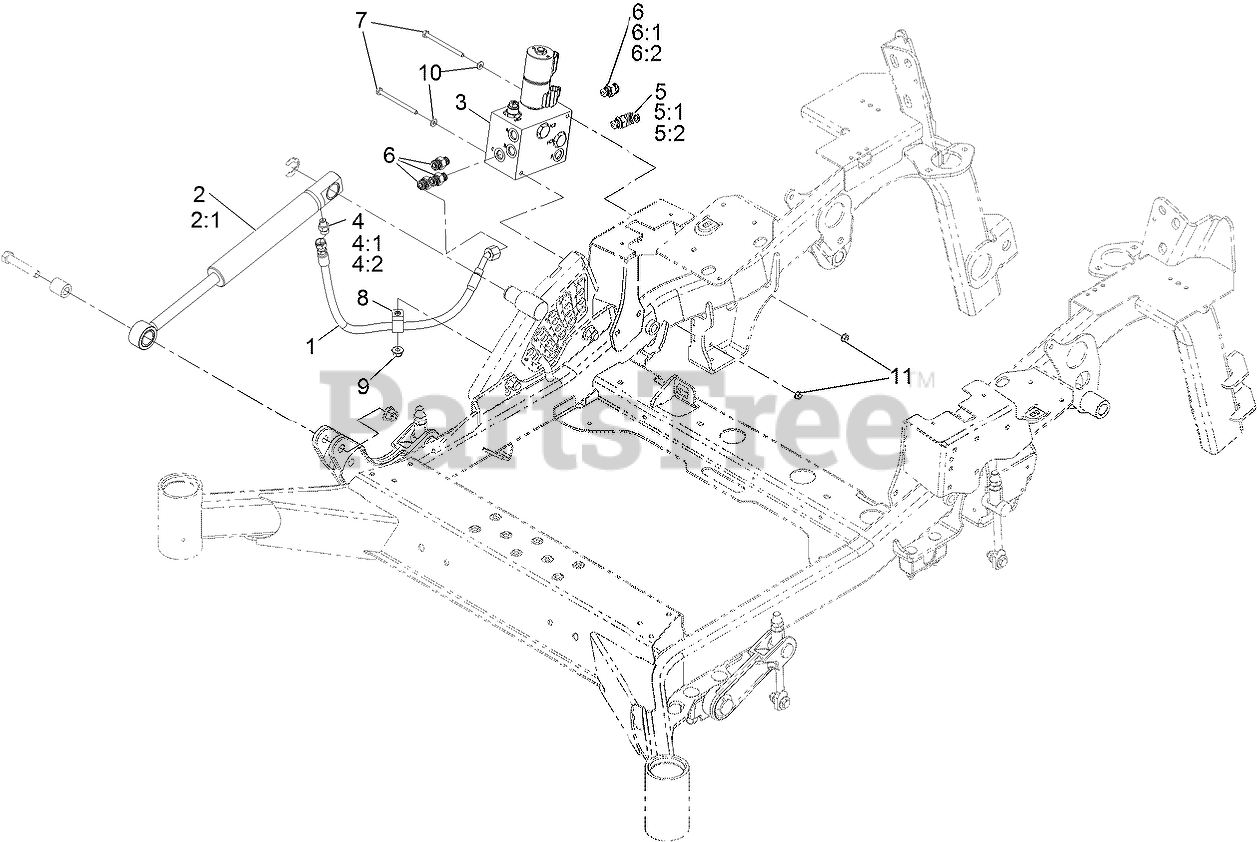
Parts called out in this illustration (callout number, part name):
1	HOSE ASM
2	CYLINDER-LIFT
2:1	CYL Repair Kit
3	LIFT AND HOLD VALVE ASM
4	FITTING-HYD, STRAIGHT
4:1	O-RING
4:2	O-RING
5	FITTING-ELBOW, 90 DEG
5:1	O-RING
5:2	O-RING
6	FITTING-STRAIGHT
6:1	O-RING
6:2	O-RING
7	SCREW-HH
8	CLIP-LOOM
9	NUT-HF, NI
10	WASHER-FLAT
